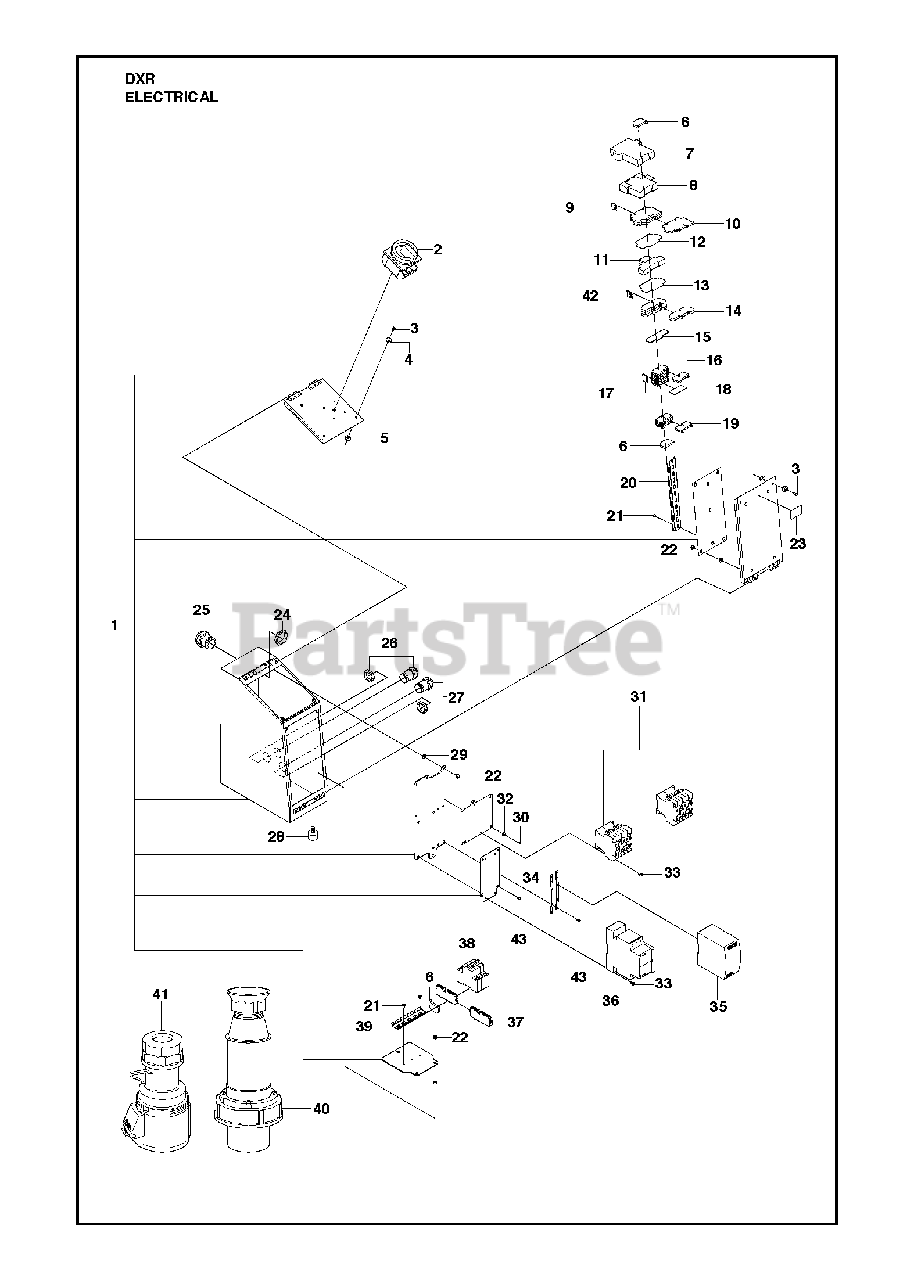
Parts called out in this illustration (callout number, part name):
7	RELAYB1, Safety relay
8	RELAYK1, Phase sequence relay
29	HEXAGON THIN NUT
